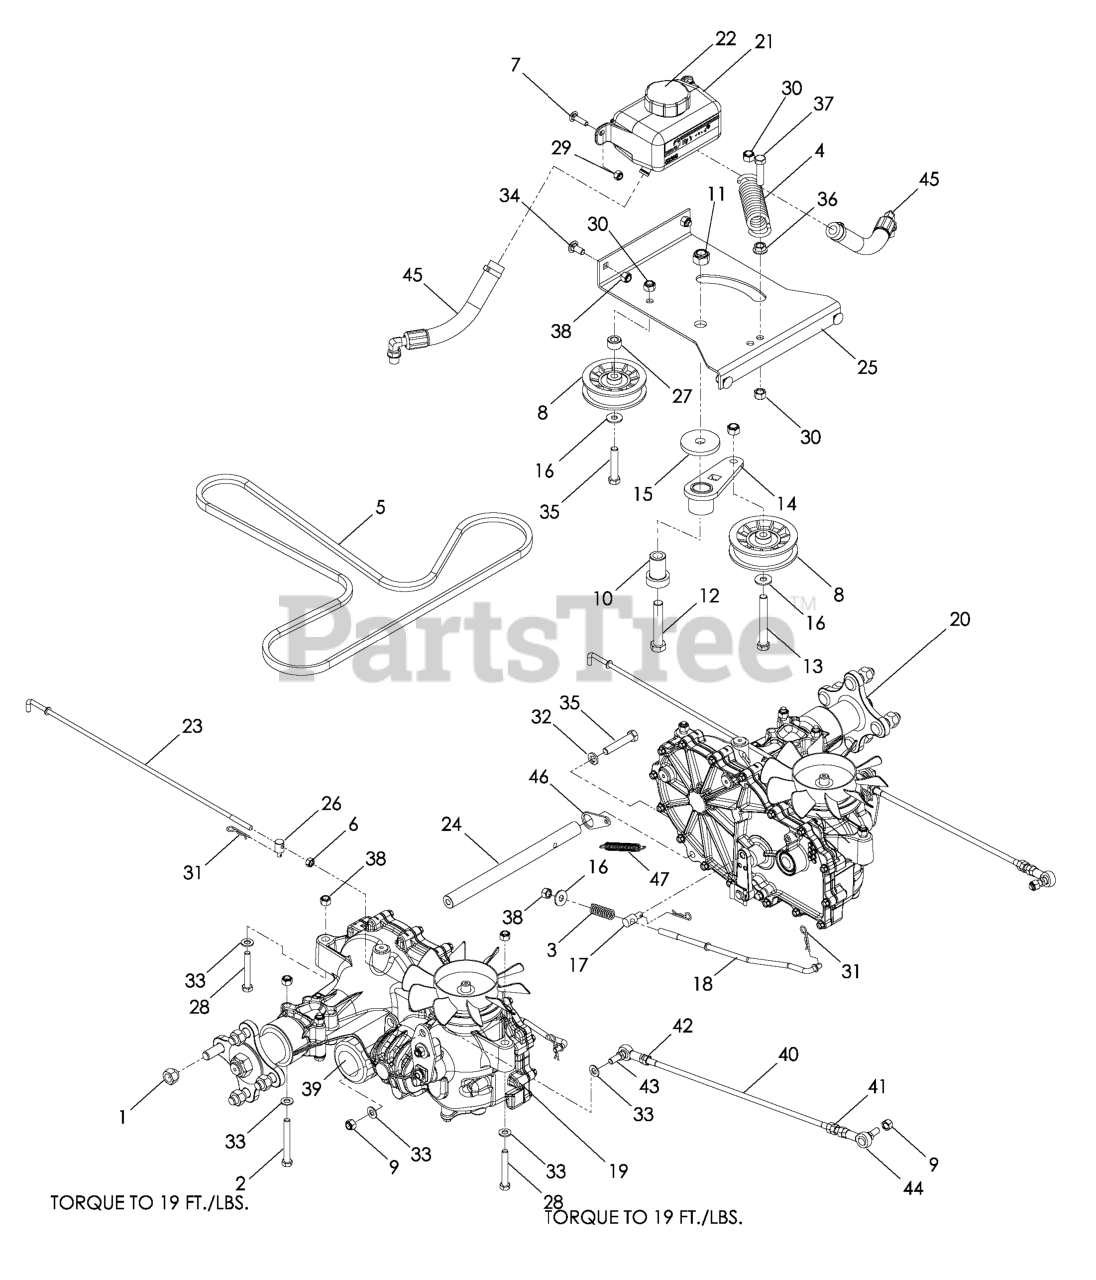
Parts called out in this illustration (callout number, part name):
1	LUG NUT 1/2F
2	HCS 5/16C X 2-3/4
5	PUMP BELT
6	NUT 1/4-28 HEX ZD
7	RHSNB, 1/4-20 X 1, GR5
8	PULLEY, IDLER RAKE & ZTR
9	NUT 5/16F NYLOC
10	IDLER SPINDLE
11	NUT 1/2-13 HEX NYLOC ZD
12	HCS 1/2C X 2 3/4
13	TAPBOLT, 3/8C X 3
14	RP.IDLER ARM WELDMENT
15	HEAVY WASHER
16	WASHER 5/16 FLAT
17	BRAKE SWIVEL
18	BRAKE LINKAGE, LOWER
19	HG_ZT2800 RIGHT SIDE
20	HG_ZT2800 LEFT SIDE
21	HG_EXPANSION TANK W/CAP 71354
22	HG_CAP 52375
23	BYPASS LINKAGE
24	2800 CROSS SUPPORT
25	IDLER PULLEY PLATE
26	SWIVEL, 1/4-28
29	NUT.1/4-20.HEX.NYLOC.ZD
30	NUT 3/8-16 NYLOC
31	HAIRPIN #2
32	SLW 3/8 STD
33	FLAT WASHER 5/16 SAE
34	BOLT 5/16C X 3/4" CARRIAGE
35	HCS 3/8C X 2
36	NUT 3/8C WHIZ
37	HCS 3/8C X 1 1/2
38	NUT 5/16 NYLOC
39	HG_FILTER, ZT4800 52114
40	DRIVE LINKAGE
42	NUT 5/16F LEFTHAND
43	SPHERICAL ROD END, LH
44	SPHERICAL ROD END, RH
46	TAB, SPRING
